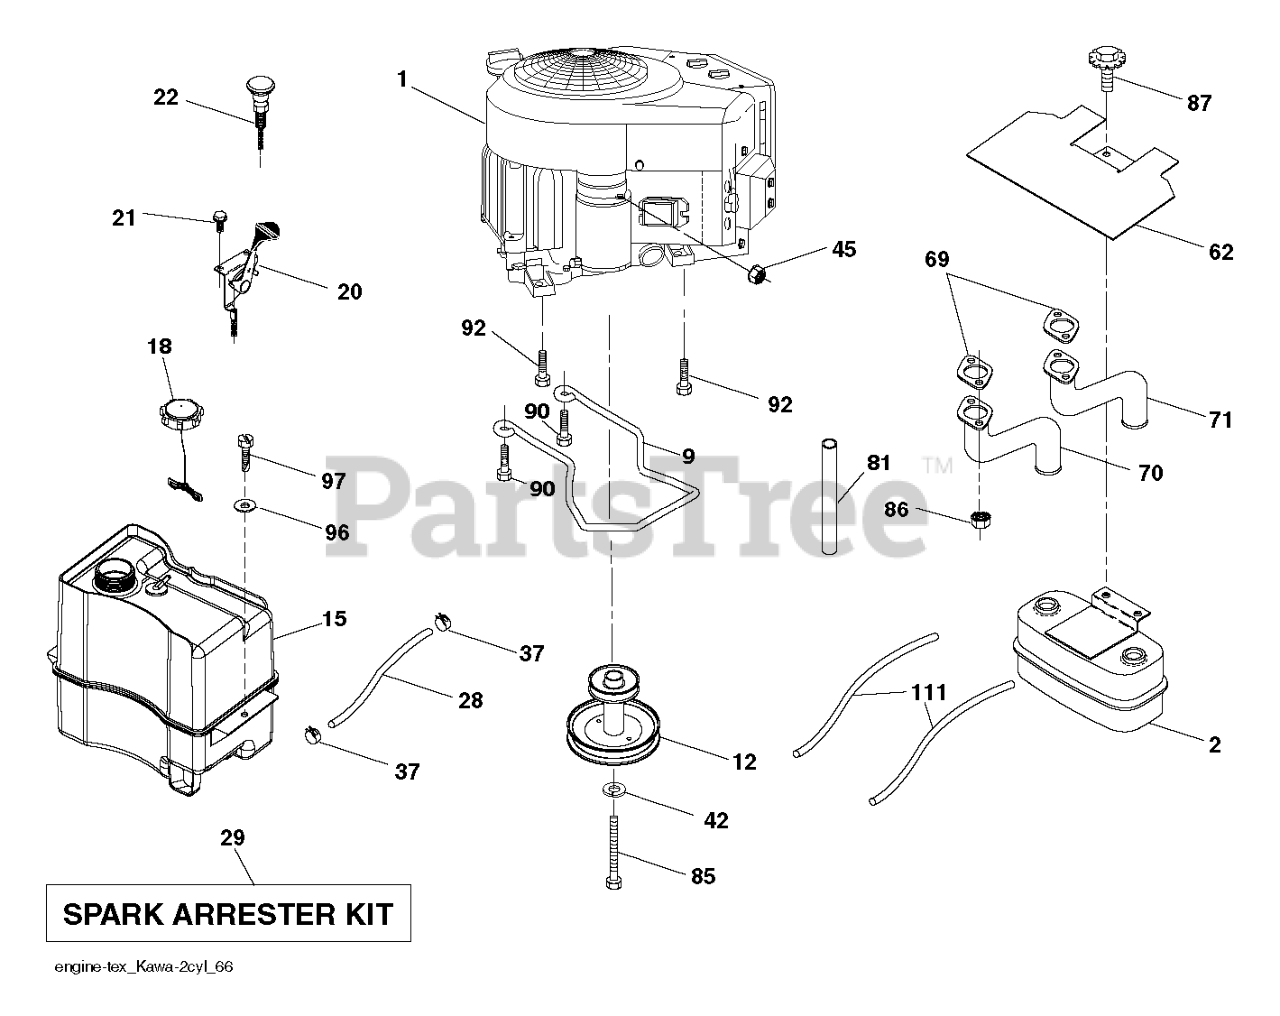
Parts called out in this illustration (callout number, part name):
2	MUFFLER.ASM.TWIN.MNTG.BRACKET
9	KEEPER.BELT.ENG.4.25"2.BLT.431
12	ENGINE.PULLEY
15	TANK.ASM.FT.2.5GAL.W/CAP.EPA17
18	CAP.2.25'.VENTED.TETHER .EPA
20	CONTROL.THROTTLE.COBRA.BLACK
21	SCREW.#10 X 0.750.BOS
22	CONTROL, CHOKE
28	HOSE 1/4" LOW PERMEATION FUEL
29	KIT.SPARK ARRESTOR 794945 B&S
37	HOSE CLAMP
42	WASHER 7/16 LOCK
45	NUT
62	SHIELD.HEAT.MUFFLER
70	TUBE.EXHAUST.LH.FR961/FR730
71	TUBE.EXHAUST.RH.FR961/FR730
81	TUBE, DRAIN OIL ASM.
85	BOLT.HEX.7/16-20X4.GR5.1.5BLUE
86	NUT.HEX.FLANGE.TOPLOCK
87	SCREW
90	SCREW 3/8-16X1
92	SCREW 3/8-16X1
97	SCREW HEXWSHR 1/4-20X3/4
111	RP PURGE LINE
